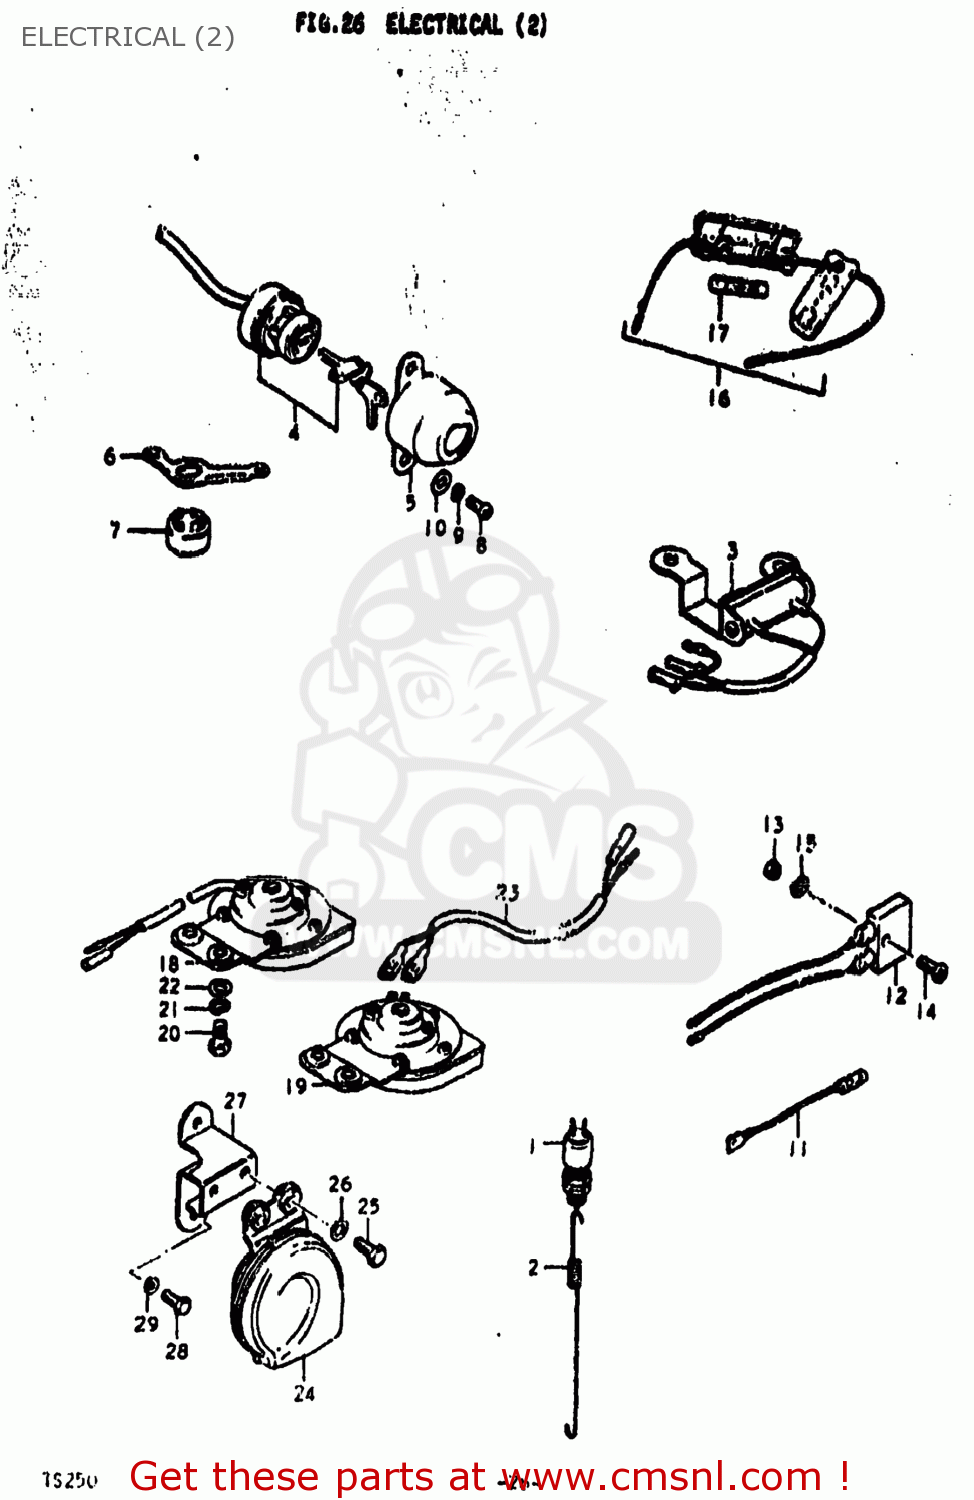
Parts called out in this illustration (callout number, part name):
1	SWITCH ASSY,BRAKE LAMP
2	SPRING
3	REGISTER ASSEMBLY,SAFETY L
4	SWITCH ASSEMBLY,IGNITION
5	BRACKET,IGNITION SWITCH
6	BRACKET, IGNITION SWITCH L,M,A
7	IGN SWITCH COVE
8	SCREW 6X12
9	LOCK WASHER
10	WASHER
11	WIRE,WIRING HARNESS LEAD
12	RECTIFIER ASSEMBLY
13	NUT
14	SCREW 5X20
15	LOCK WASHER
16	BOX ASSEMBLY,FUSE
17	FUSE(15A)
18	HORN ASSEMBLY
19	HORN ASSEMBLY
20	BOLT
21	LOCK WASHER
22	WASHER
23	WIRE,HORN LEAD
24	HORN ASSY
25	BOLT
26	WASHER
27	BRACKET,HORN
28	SCREW 6X12
29	LOCK WASHER
